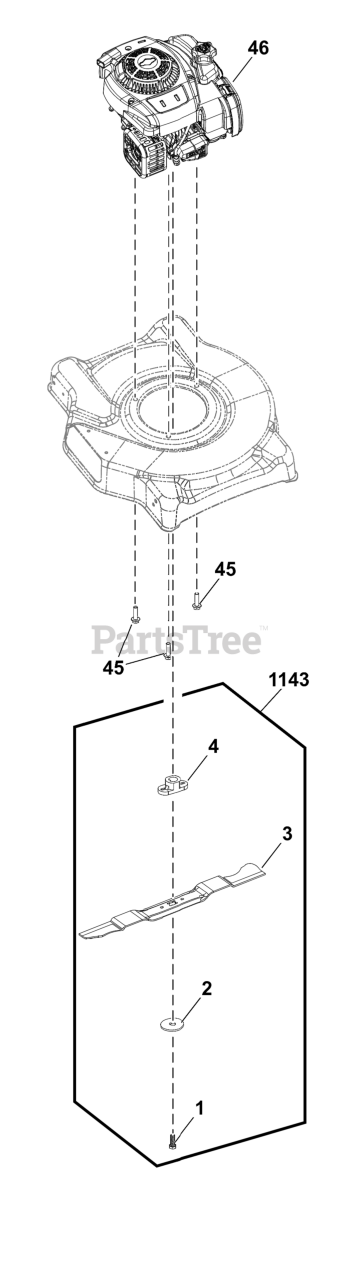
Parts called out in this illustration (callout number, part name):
1	BOLT, Blade
2	WASHER
3	BLADE, Mower
4	ADAPTER, Blade
45	BOLT
46	ENGINE
1143	KIT, Blade
